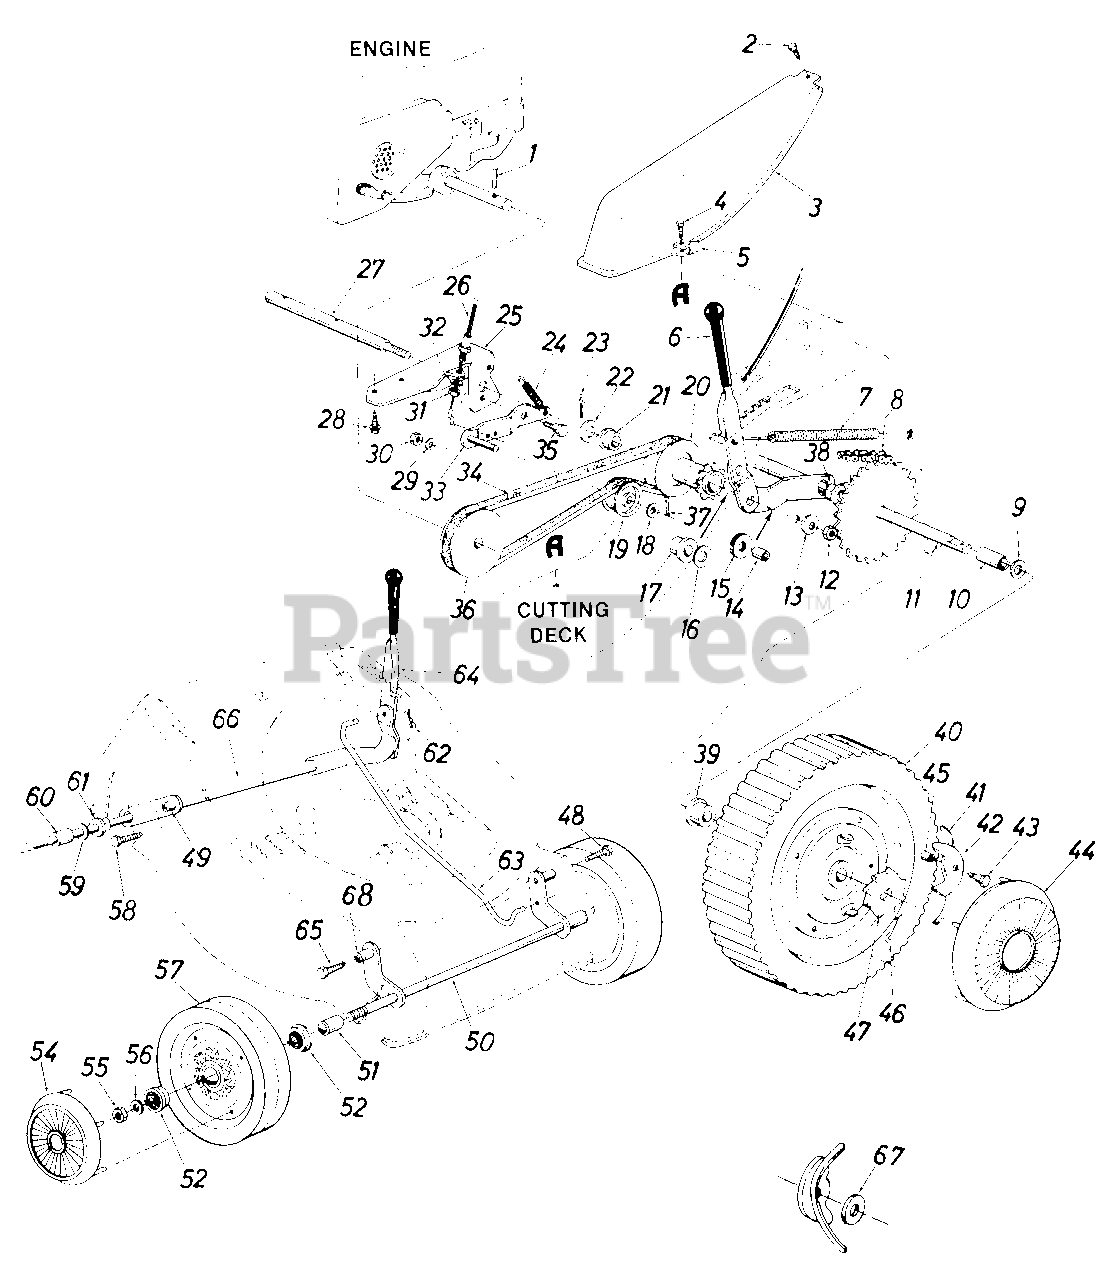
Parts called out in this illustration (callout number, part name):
1	Spring Pin Roll 3/16" Dia. x 1.50" Lg.
2	Hex Wash. Hd. AB-Tap Scr. #10 x .50" Lg.
3	Belt Cover
4	Hex B-Tap Scr. 1/4 x .38" Lg.
5	Cable Clip
6	Grip Black
7	Extension Spring .50 O.D. x 4.25 Lg.
8	#48 Chain 1/2 Pitch x 34 Links - E
9	Fl-Wash. .531 I.D. x .93 O.D. x .05
10	Spacer .75 I.D. x .88 O.D. x 1.41 Lg.
11	Axle Rear
12	Hex Jam Nut 3/8-16 Thd.
13	Bell-Wash. .400" I.D. x .860" O.D. x .060
14	Spacer .395 I.D. x .503 O.D. x .562" Lg.
15	Rubber Washer .51" I.D. x 1.00" O.D. x .25
16	Fl-Wash. .390 I.D. x 1.000 O.D. x .030 - H.T.
17	Flange Brg. .503 I.D. Plastic
18	Fl-Wash. .531 I.D. x.93 O.D. x .05
19	Flat Idler Pulley
20	3.00" O.D. Split Pulley with Sprocket Ass'y.
21	Flange Brg. .503 I.D. Plastic
22	Fl-Wash. .531 I.D. x .93 O.D. x .05
23	Cot. Pin 3/32 Dia. x 1.00" Lg.
24	Extension Spring .33" O.D. x 1.12" Lg.
25	Support Bracket
26	Clutch Control Cable
27	Pulley Shaft .500" Dia.
28	Hex Wash. Hd. B-Tap Scr. 5/16 x .50 Lg.
29	L-Wash. 1/4 I.D.
30	Hex Nut 1/4-20 Thd.
31	Hex Jam Nut 1/4-28 Thd.
32	L-Wash. 1/4 I.D.
33	Idler Brkt.
34	V-Belt 1/2 x 33" Lg.
35	Shld. Bolt .375 Dia. x 1.71
36	1/2 V-Pulley .500 I.D. x 2.59 O.D.
37	Cot. Pin 1/8 Dia. x 1.00 Lg.
38	Hex. Flange Brg. .506 I.D. (Plastic)
39	Flange Ball Brg.
40	Rear Wheel Ass'y. Comp.
41	Nylon Spring
42	Pawl - Rear Wheel
43	Truss Mach. Scr. 1/4-20 x .75 Taptite Thds.
45	Spacer .260 I.D. x .345 O.D. x .280 Lg.
46	Cot. Pin 1/8 Dia. x 1.00 Lg.
47	Ratchet - Rear Wheel
48	Hex Wash. Hd. TT-Tap Scr. 3/8-16 x 1.00 Lg.
49	Spacer .385 I.D. x .503 O.D. x .270 Lg.
50	Front Axle Ass'y.
51	Spacer .516 I.D. x .670 O.D. x .860 Lg.
52	Flanged - Ball Brg.
55	Hex L-Nut 1/2-20 Thd.
56	Fl-Wash. .510 I.D. x 1.000 O.D. x .125
57	Wheel Ass'y. Complete 8 x 1.75
58	Hex Wash Hd. TT-Tap Scr. 3/8-16 x 1.00
59	Fl-Wash. .531 I.D. x .93 O.D. x .05
60	Spacer .526 I.D. x .690 O.D. x .640 Lg.
61	Hex Flange Brg. .506 I.D. (Plastic)
62	Cot. Pin 3/32 Dia. x 1.00 Lg.
63	Linkage Rod .38 Dia.
64	Height Adj. Handle
65	Hex Wash. Hd. TT-Tap Scr. 3/8-16 x 1.00
66	Axle Ass'y.
67	Fl-Wash. .28 I.D. x .75 O.D. x .030
68	Spacer .395 I.D. x .503 O.D. x .562 Lg.
